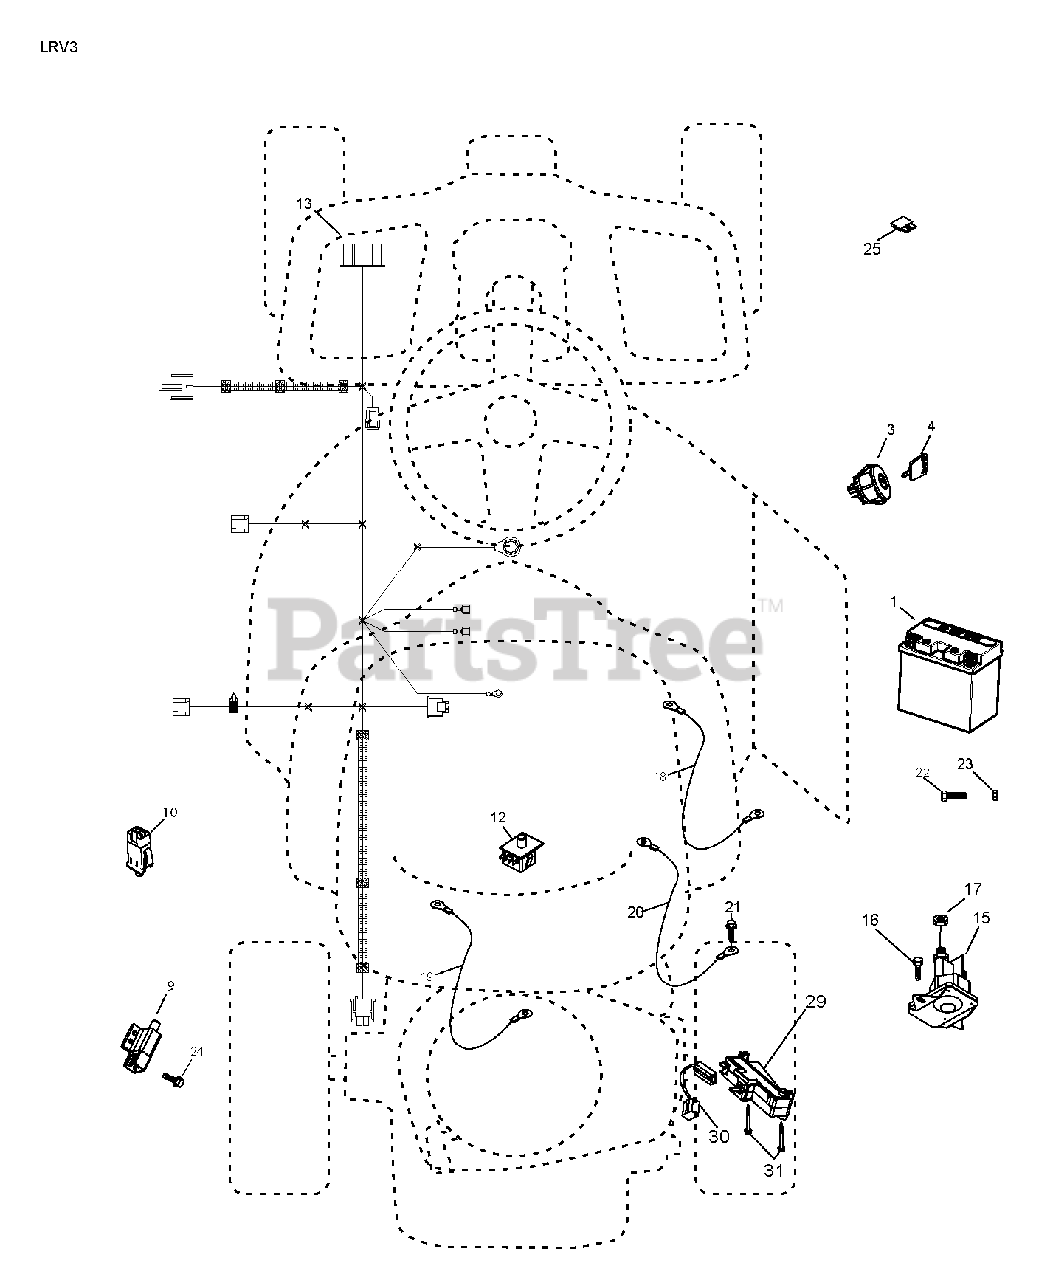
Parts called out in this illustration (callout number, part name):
1	BATTERY.6A.12V.LEOCH
3	SWITCH.IGN.DELTA.W.LGH.ROS
4	KEY.CHAIN.BLISTER.PACK.GEN.INT
9	SWITCH INTERLOCKT
10	SWITCH INTERLOOK PUSH-IN
12	SWITCH.SEAT.DP W/RAMPS
13	ELECTRICAL.LRVB.GEARDRIVE
15	SOLENOID.W/BRASS.PLUNGER
16	SCREW
17	NUT
18	CABLE.BATTERY.20.RED.8 AWG
19	CABLE.STARTER.6GA.11"RED
20	CABLE GROUND 6 GA. 12" BLACK
21	SCREW 5/16"
22	SCREW.HEX.M5X0.8.9MM (2 2)
23	NUT.M5.(.393X.275)
24	SCR #10-24 X .75 SKT HD BLK
29	MODULE.REVERSE.ROS
30	JUMPER.PIGTAIL.ROS.LRVB
31	SCREW.PLASTITE
